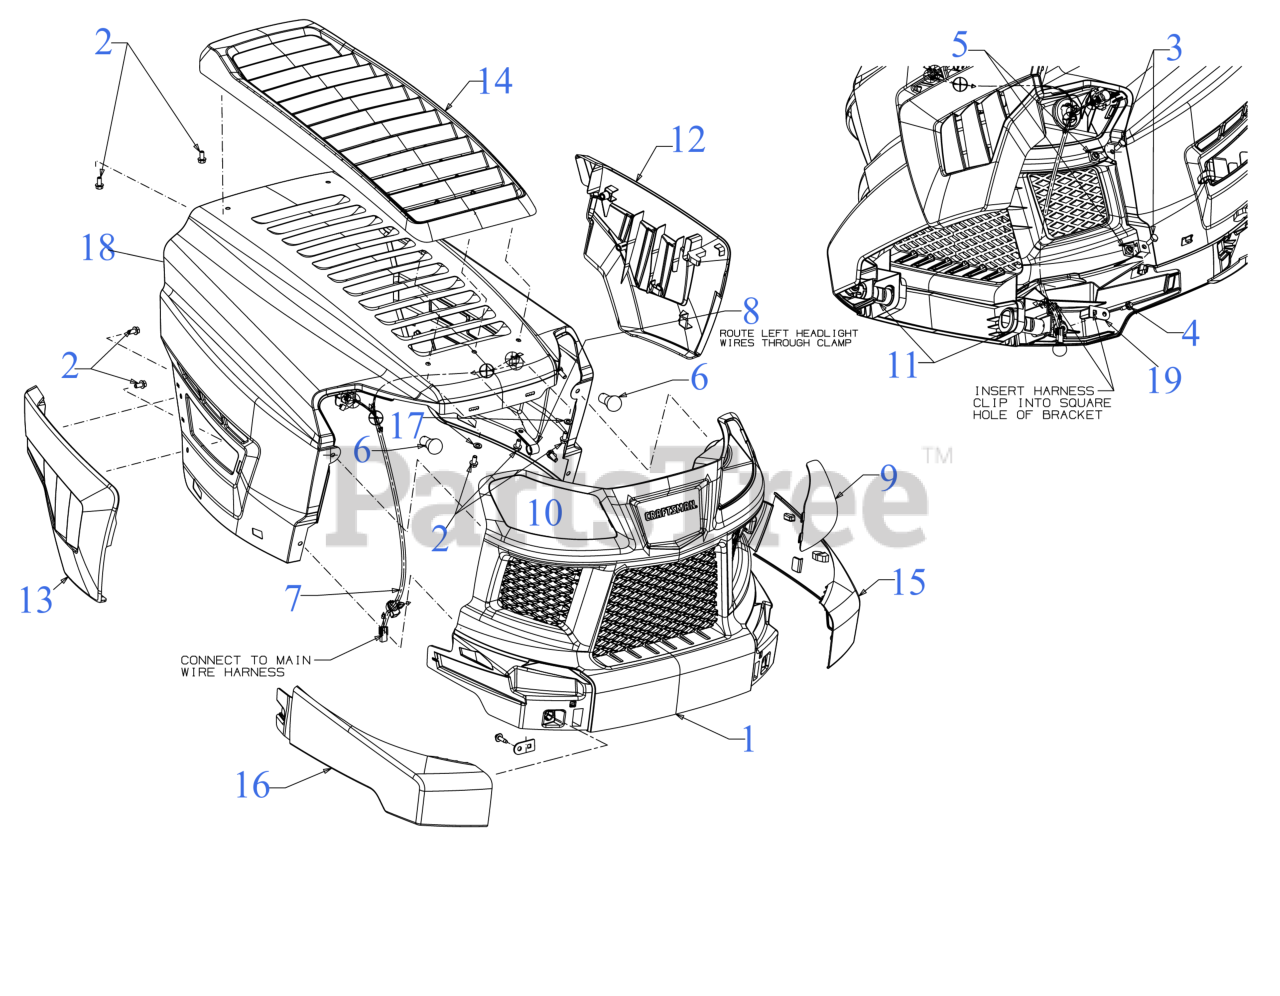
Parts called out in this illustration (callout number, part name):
1	GRILLE
2	HEX SCREW 1/4-15 x .50
3	SCREW 1/4-20 x .62 SPEC GR5
4	SCREW 1/4-10 x .750
5	SQUARE NUT 1/4-20
6	MINIATURE LAMP-12V #1156
7	HEADLIGHT HARNESS
8	HEADLIGHT HARNESS CLAMP
9	GRILLE LENS (LH)
10	GRILLE LENS (RH)
11	HOOD PIVOT PIN
12	HOOD SIDE COVER (LH)
13	HOOD SIDE COVER (RH)
14	HOOD SCOOP
15	GRILLE PANEL (LH) (LIBERTY RED)
16	GRILLE PANEL (RH) (LIBERTY RED)
17	FLAT WASHER
19	HARNESS CLIP BRACKET
